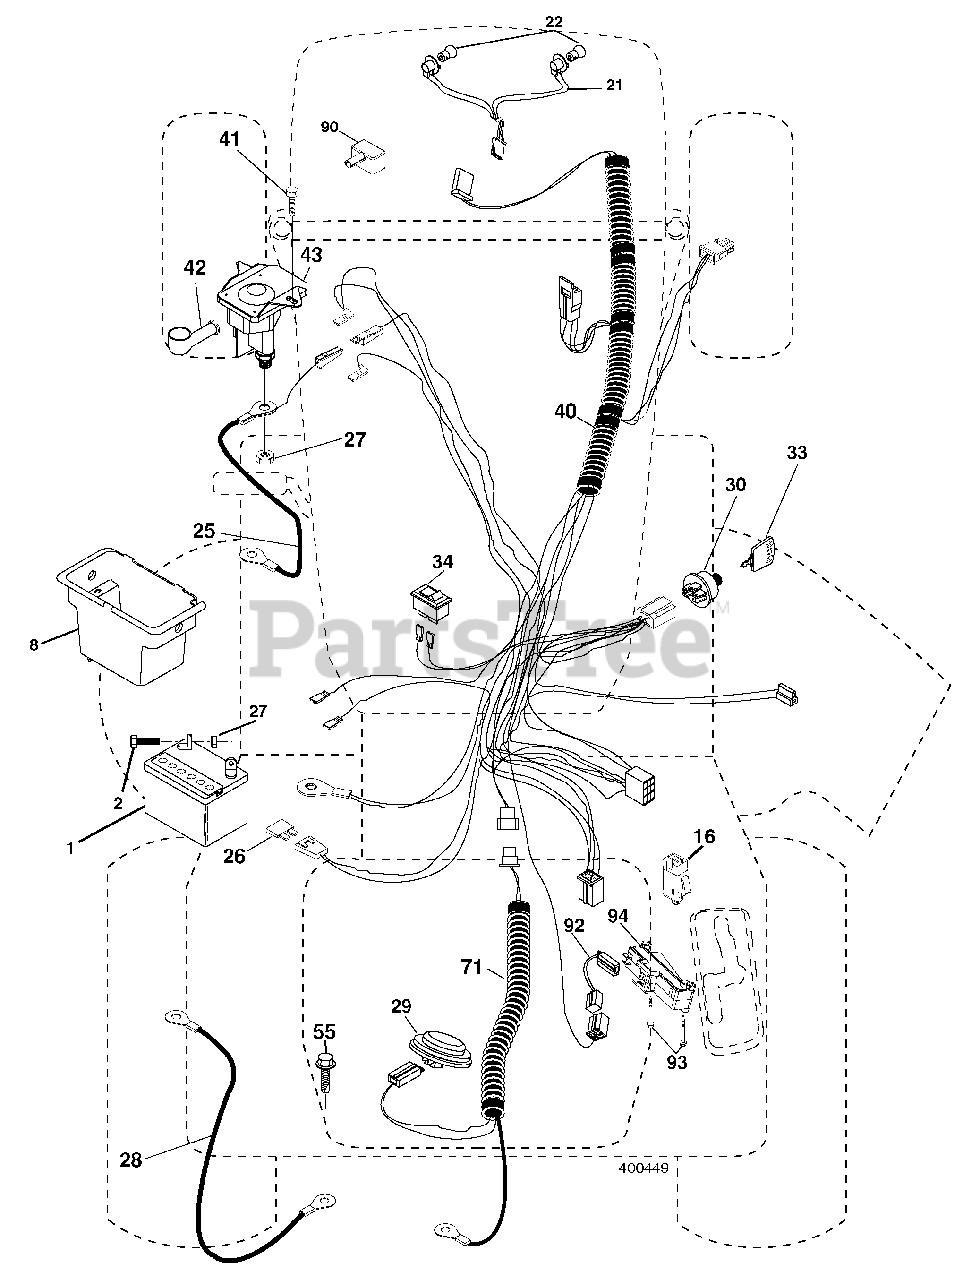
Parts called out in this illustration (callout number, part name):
1	Battery
2	Bolt Hex Head 1/4-20 x 3/4
8	Box Battery
16	Switch Interlock Push-In
21	Harness Socket Light W/4152J
22	Bulb Light
25	Cable Starter
26	Fuse
27	Nut Keps Hex 1/4-20 unc
28	Cable, Ground
29	Switch, Seat
30	Switch, Ign
33	Key, Ignition
34	Switch Light / Reset
40	Harness Ign.
41	Screw Thd Cut 1/4-20 x 1/2
42	Cover, Terminal
43	Solenoid
55	Screw Thdrol 5/16-18 x 3/4 TYTT
71	Harness Ign. Dash
90	Cover Terminal Battery
92	Harness Pigtail
93	Screw Plastite 10-14 x 2.0
94	Module Reverse ROS
